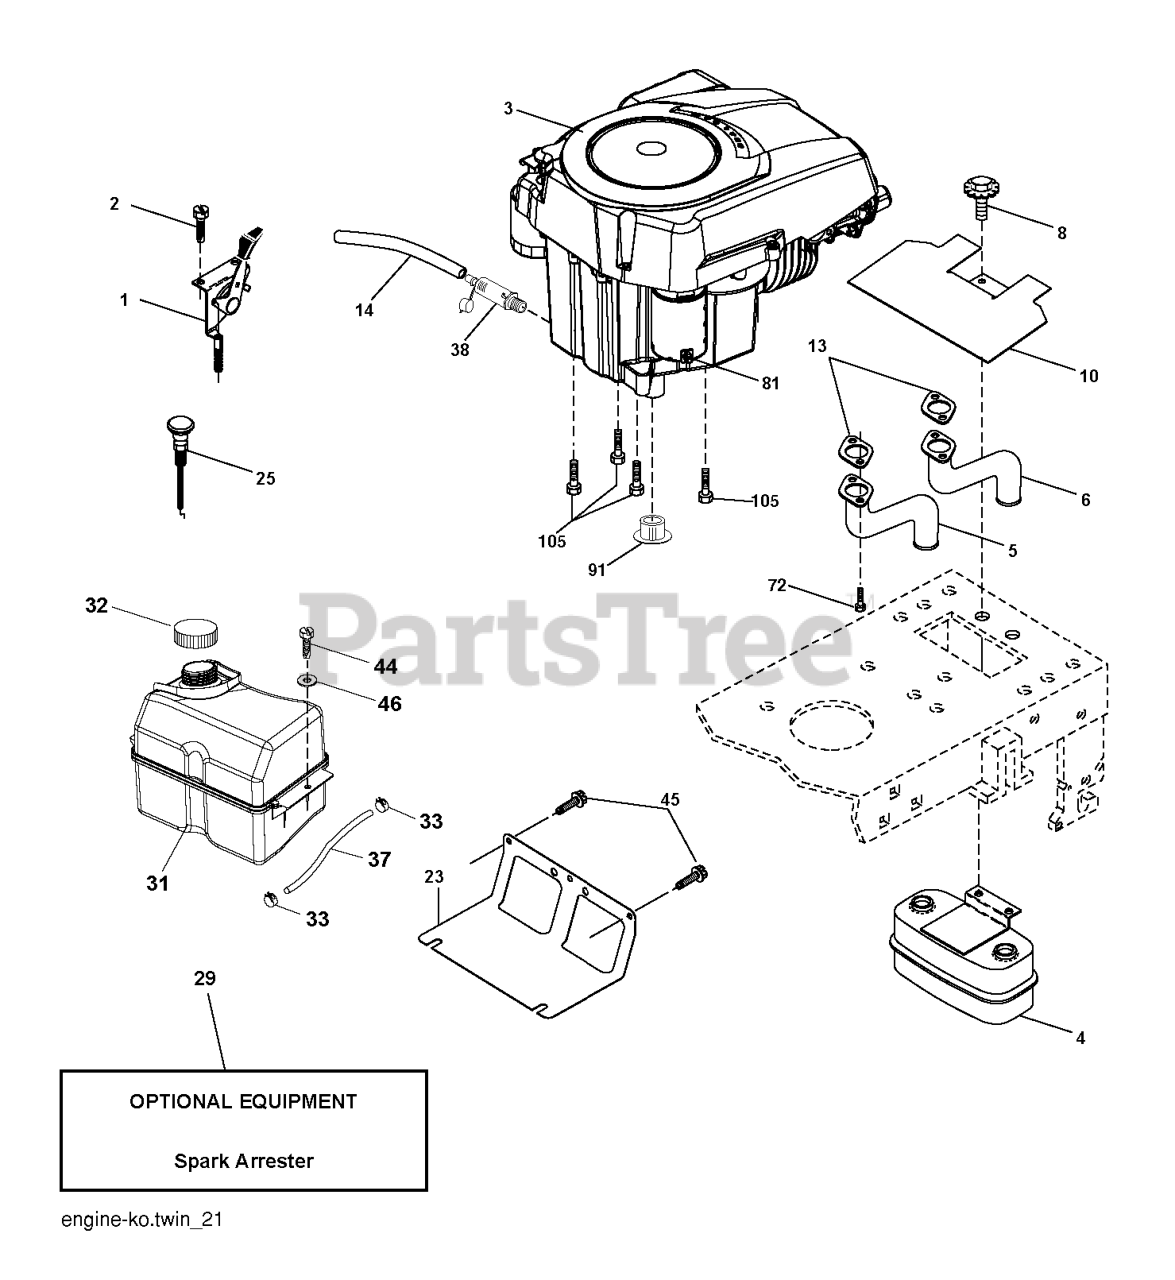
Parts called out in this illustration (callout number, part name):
1	THROTTLE CONTROL
2	SCREW.#10 X 0.750.BOS
4	MUFFLER.TWIN.CYL.LOW.TONE
5	RP.PIPE-EXHAUST LH
6	RP.PIPE-EXHAUST RH
8	BOLT.5/16-18UNCX3/4 W/SEMS.BLK
10	RP SHIELD HEAT MUFFLER
13	GASKET.EXHAUST.KOHL.CV18-CV26
14	TUBE, DRAIN OIL ASM.
23	SHIELD.BROWNING.DBR.GUARD
25	CONTROL, CHOKE
29	KIT.SPARK ARRESTOR 794945 B&S
31	TANK.ASM.FUEL.FR.2.5GA.
32	FUEL CAP
33	HOSE CLAMP
37	LINE.FUEL.20
38	PLUG DRAIN OIL EASY
44	SCREW HEXWSHR 1/4-20X3/4
45	SCREW, 3/8-16X3/4
72	SCREW.SOCKET HD.5/16-1
81	NUT
91	BUSHING.1.375OD
105	SCREW 3/8-16X1
